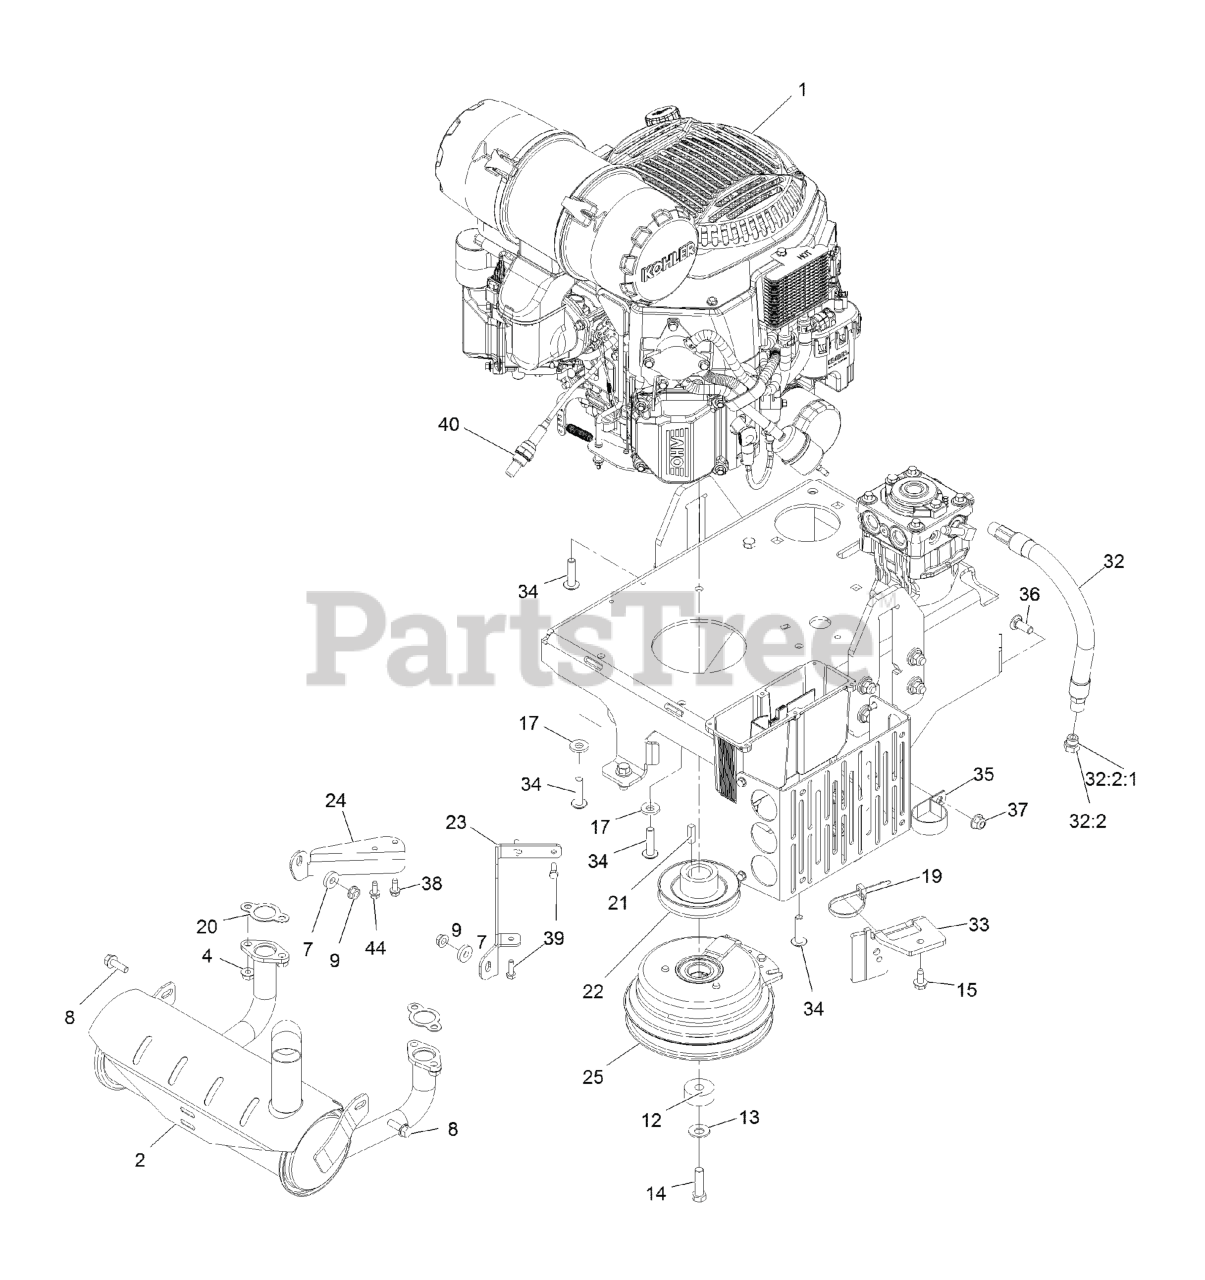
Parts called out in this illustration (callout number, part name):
4	NUT-FLANGE
8	SCREW-HHF
12	KEEPER-CLUTCH
13	WASHER-SPRING
14	SCREW-HH
15	Screw-HWH 5/16-18 X 3/4 Tf
17	WASHER-BELLEVILLE
19	TIE-CABLE
20	GASKET-EXHAUST
23	MOUNT, MUFFLER-LT
24	MOUNT, MUFFLER-RT
25	CLUTCH-200 FT-LB, 1.125 B
32	OIL DRAIN HOSE ASM
32:2	PLUG-HH
32:2:1	O-RING
33	BRACKET-ANCHOR, CLUTCH
34	SCREW-BHTF
35	CLAMP-R
36	SCREW-CARR
37	NUT-HF, NI
38	SCREW-HWHTF
39	SCREW-HH M6-1 X 20Mm W/Patch
40	SENSOR-OXYGEN
44	SCREW-HWHTF
